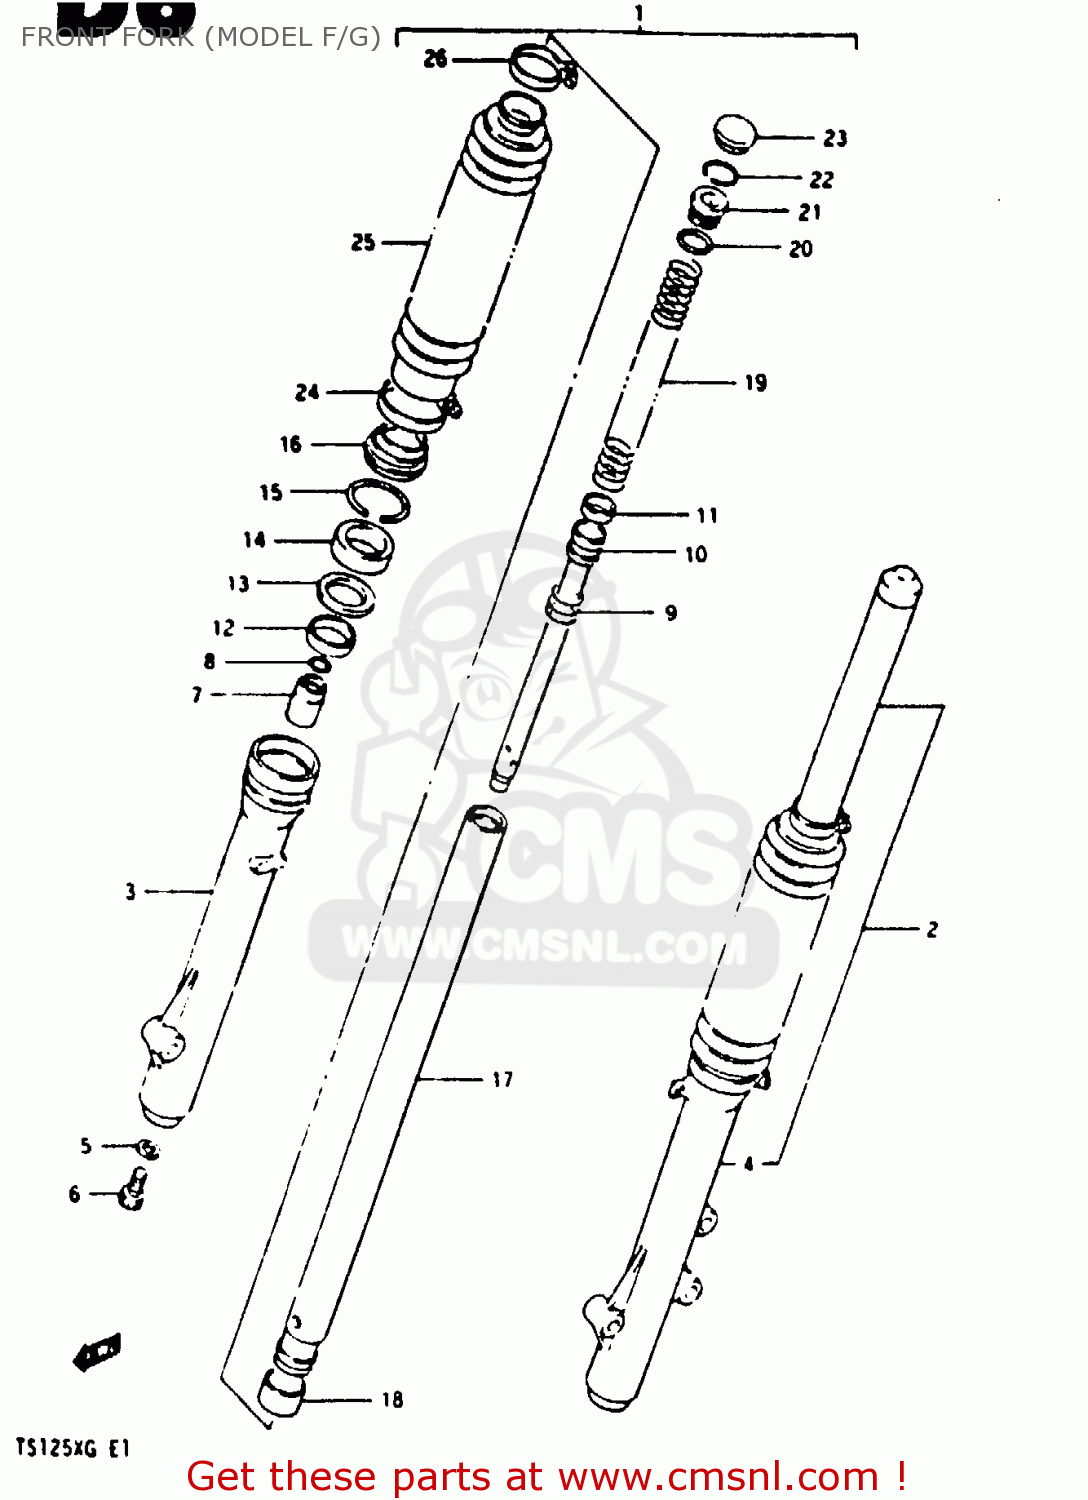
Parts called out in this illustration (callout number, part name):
1	DAMPER ASSY, RH
2	DAMPER ASSY, LH
3	TUBE,OUTER,R
4	TUBE,OUTER,L
5	GASKET (NAS)
6	BOLT(8X27)
7	PIECE,OIL LOCK
8	RING,STOPPER
9	SPRING,REBOUND
10	CYLINDER
11	RING,PISTON
12	BUSH,GUIDE
13	SPACER,SEAL
14	OIL SEAL,FRONT FORK
15	CIRCLIP,FORK OIL SEAL
16	SEAL,DUST
17	TUBE,INNER
18	PISTON
19	SPRING
20	O RING
21	SPRING SEAT B
22	RING,STOPPER
23	CAP
24	BAND
25	BOOT
26	BAND
